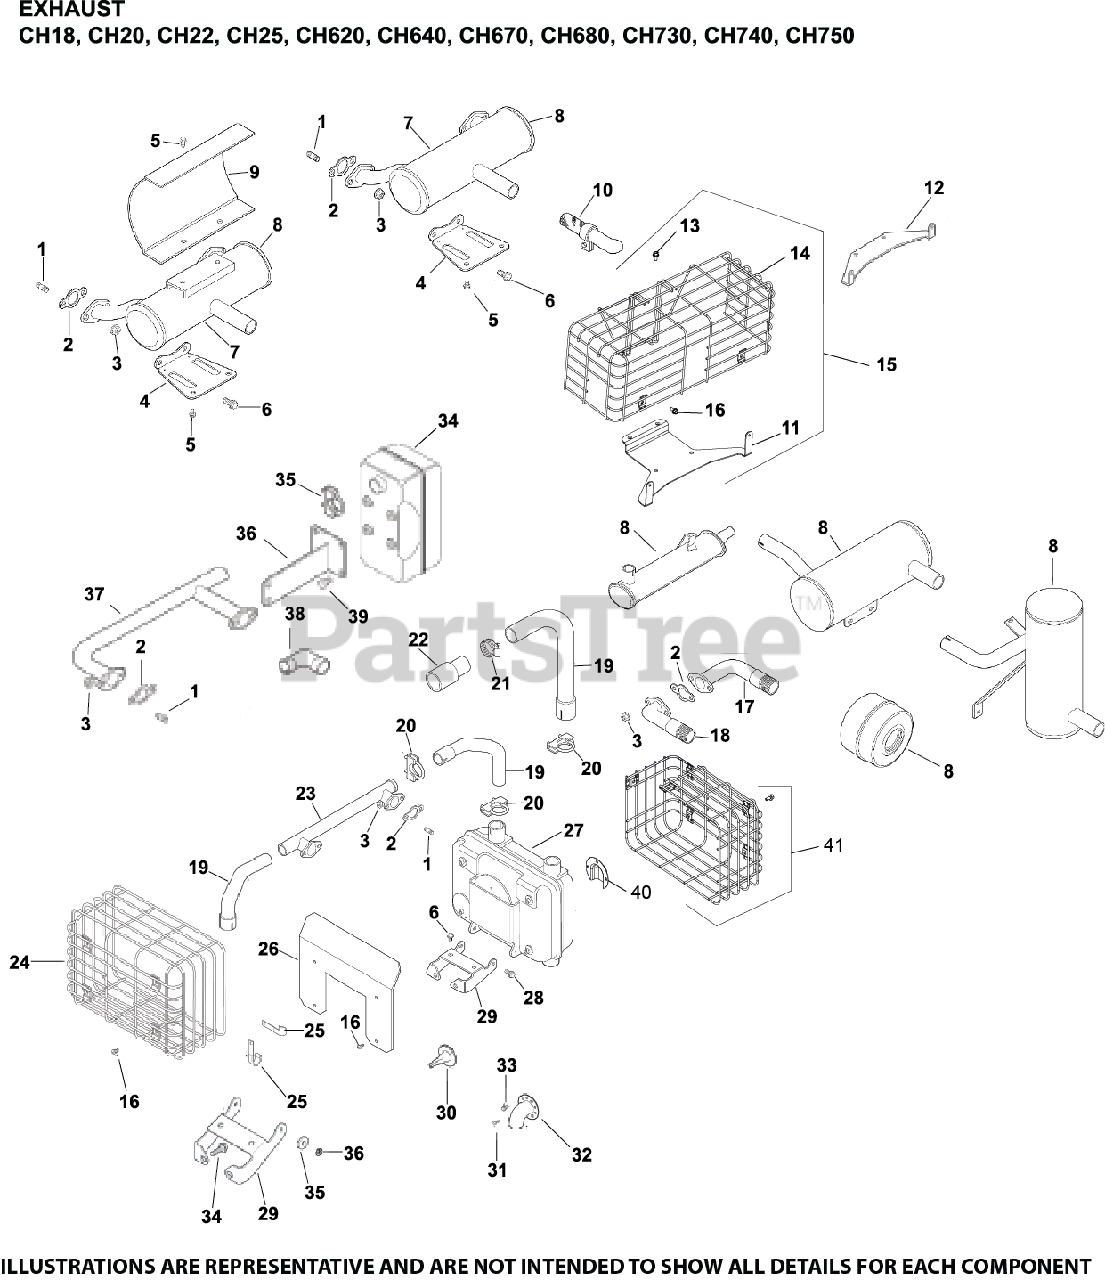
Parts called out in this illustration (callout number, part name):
1	STUD, EXHAUST-USE 25 072 24-S
2	GASKET, EXHAUST
3	NUT, FLG M8X1.25
4	BRACKET, MUFFLER
5	SCREW, FLG M6X1.0X12
6	SCREW, FLG M8X1.25X20
8	MUFFLER USE 24 068 130-S
